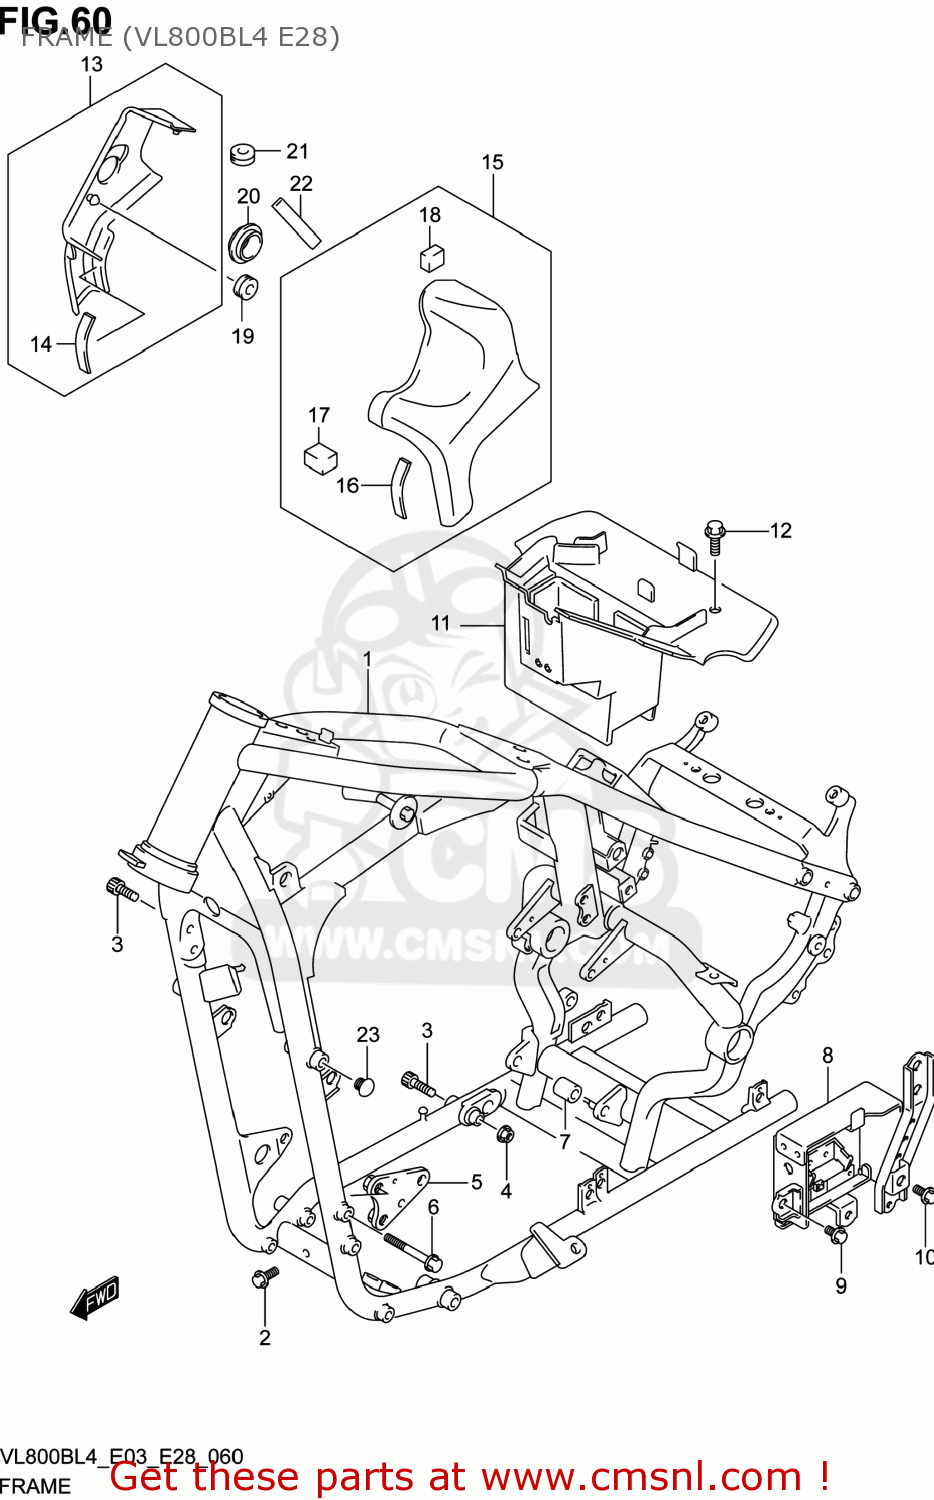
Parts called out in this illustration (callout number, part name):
1	FRAME(BLACK)
2	BOLT
3	BOLT
4	NUT
5	PLATE,ENGINE MOUNT NO.1,L
6	BOLT(8X65)
7	SPACER,ENG MTG LR
8	HOLDER,ELECTRIC PARTS
9	BOLT
10	BOLT
11	HOLDER,ELECTRIC PARTS
12	BOLT(6X16)
13	COVER,FRAME HEAD,R(BLACK)
14	CUSHION,FR FENDER
15	COVER,FRAME HEAD,L(BLACK)
16	CUSHION,FR FENDER
17	CUSHION,FR FENDER SIDE
18	CUSHION
19	CUSHION
20	CAP
21	CUSHION
22	CUSHION,RADIATOR COVER INNER
23	CAP(OD:14)
